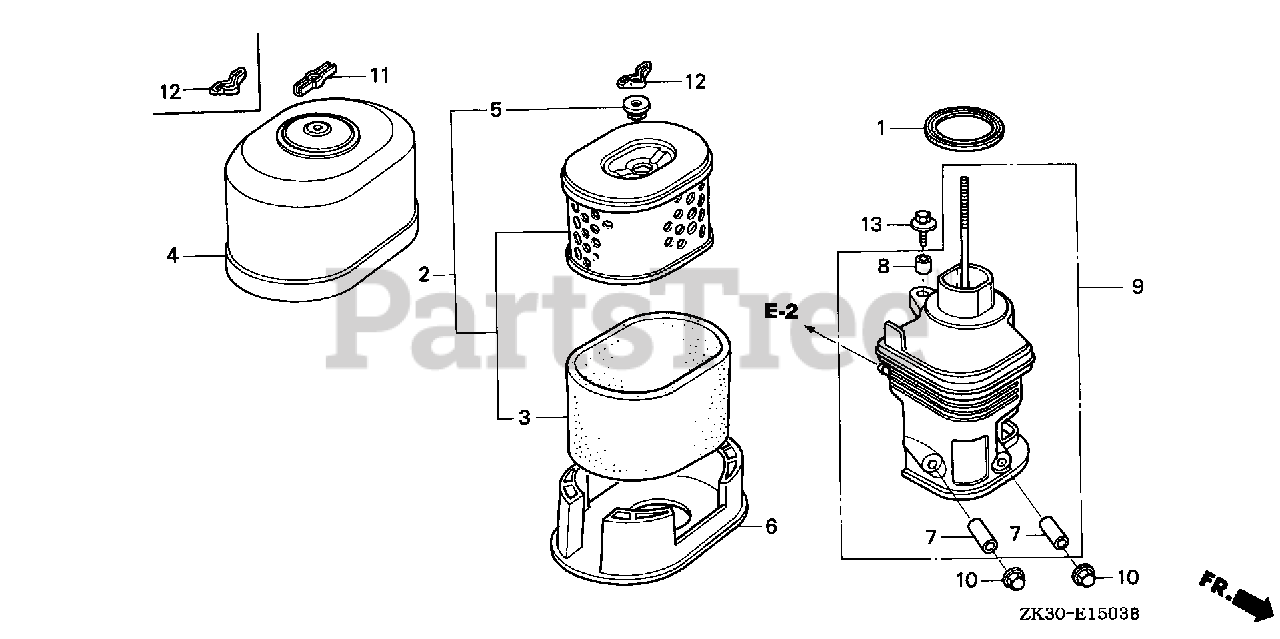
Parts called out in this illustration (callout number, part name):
1	GASKET, ELBOW
2	ELEMENT, AIR CLEANER
3	FILTER (OUTER)
4	COVER, AIR CLEANER (STD)
5	GROMMET, AIR CLEANER
6	NOSE, MUFFLER
7	COLLAR, AIR CLEANER
8	COLLAR B, AIR CLEANER
9	ELBOW, AIR CLEANER
10	NUT, FLANGE (6MM)
12	NUT, TOOL BOX SETTING
13	BOLT-WASHER (6X22)
